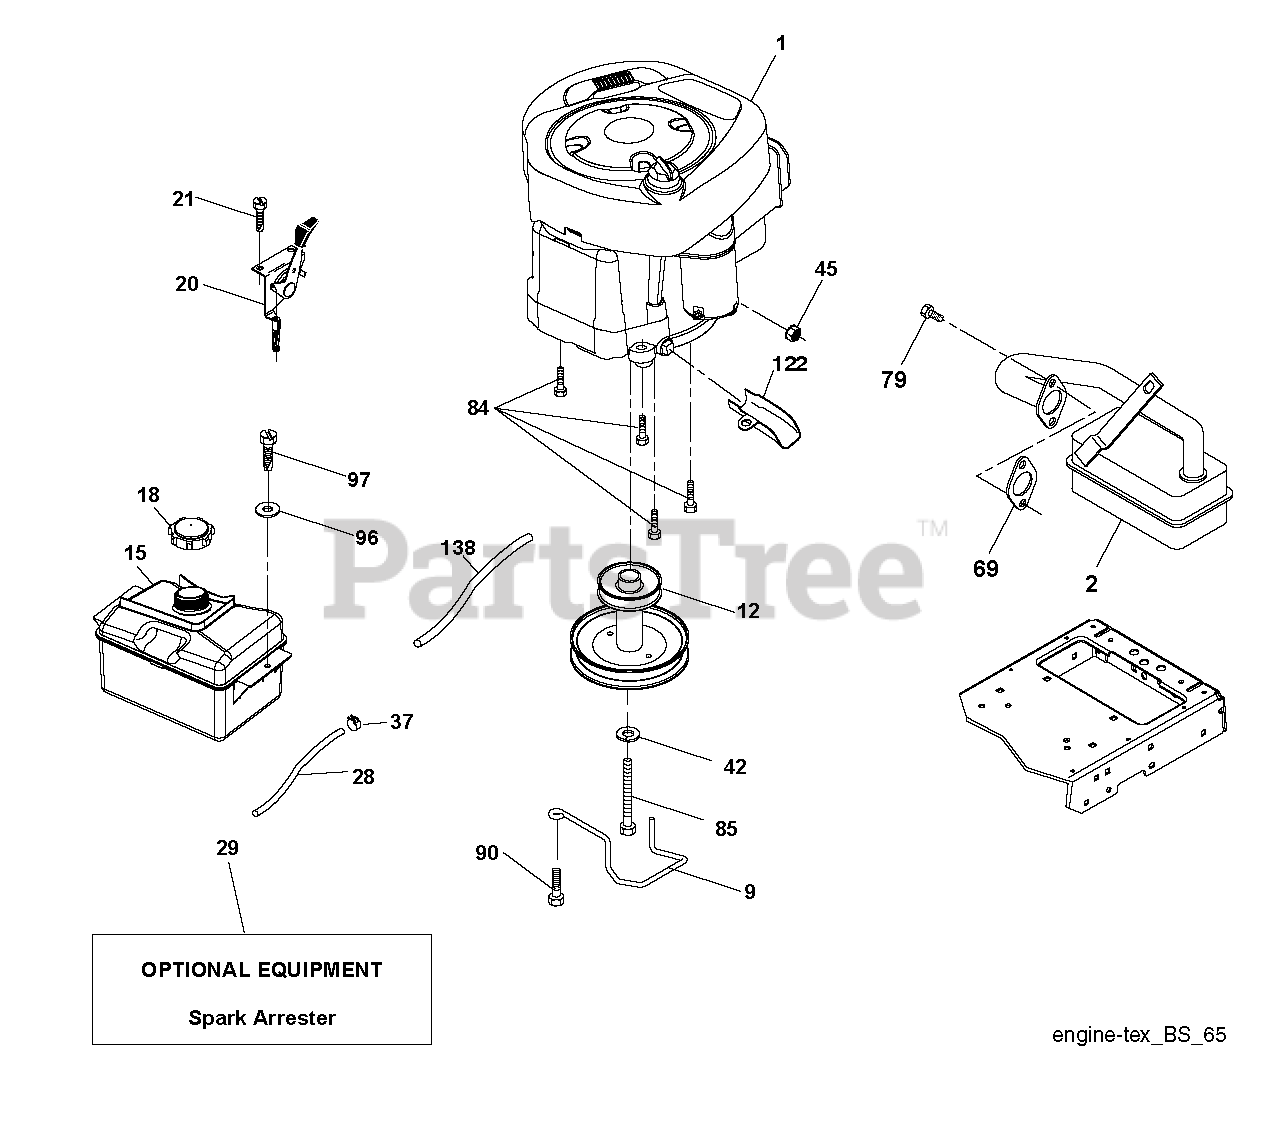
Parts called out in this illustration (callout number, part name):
2	MUFFLER.LT.BRIGGS.14HP.IC/OHV
9	KEEPER.BELT.ENGINE.3.25 (3 2)
12	PULLEY.ENG.CL.MECH.SLVR.LT/YT
15	TANK.ASM.1.5GAL.FRT.W/CAP.EPA
18	CAP.FUEL.2 WAY VENT
20	CONTROL.TH/CK.C.
21	SCREW.#10 X 0.750.BOS
28	LINE.FUEL.20"FRONT.EMI
29	KIT.SPARK ARRESTOR 794945 B&S
37	HOSE CLAMP
42	LOCKWASHER
45	NUT
69	REPL BY 532 27 22-93
79	SCREW.SOCKET HD.5/16-1
84	SCREW.3/8-16
85	BOLT HEX 7/16-20X4-1/4"
90	SCREW 3/8-16X1
97	SCREW HEXWSHR 1/4-20X3/4
122	EXTENSION DRAIN OIL
138	RP PURGE LINE
